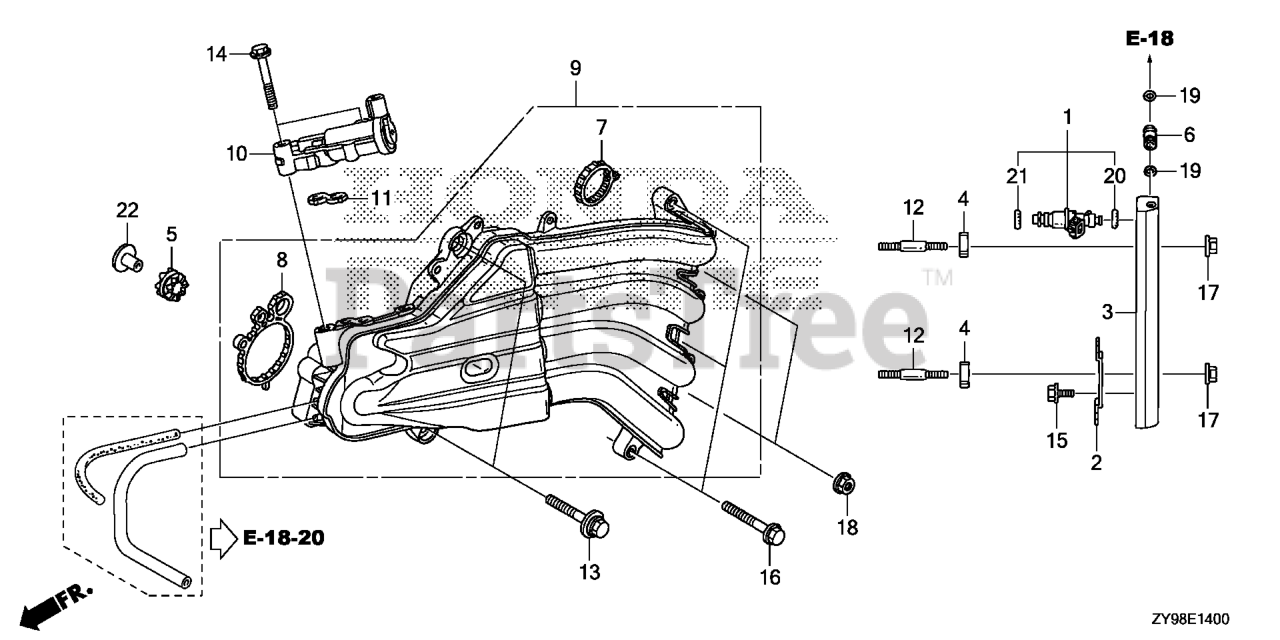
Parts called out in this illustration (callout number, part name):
1	INJECTOR ASSY., FUEL
2	CLIP, INJECTOR
3	LINE, FUEL
4	INSULATOR, FUEL PIPE
5	GROMMET, VAPOR SEPARATOR
6	JOINT, FUEL PIPE
7	GASKET, IN. MANIFOLD
8	GASKET, THROTTLE BODY
9	MANIFOLD, INLET
10	VALVE ASSY., ELECTRONIC AIR CONTROL
11	GASKET, ELECTRONIC AIR CONTROL VALVE
12	BOLT, STUD (6X40)
13	BOLT-WASHER (8X35)
14	BOLT, FLANGE (8X45)
15	BOLT, FLANGE (6X10)
15	BOLT (6X10)
16	BOLT, FLANGE (8X35)
17	NUT, FLANGE (6MM)
18	NUT, FLANGE (8MM)
19	O-RING (7.8X1.9) (ARAI)
20	O-RING (7.47X3.6)
21	O-RING (7.45X3.61) (NOK)
22	COLLAR (8.5X14.5)
